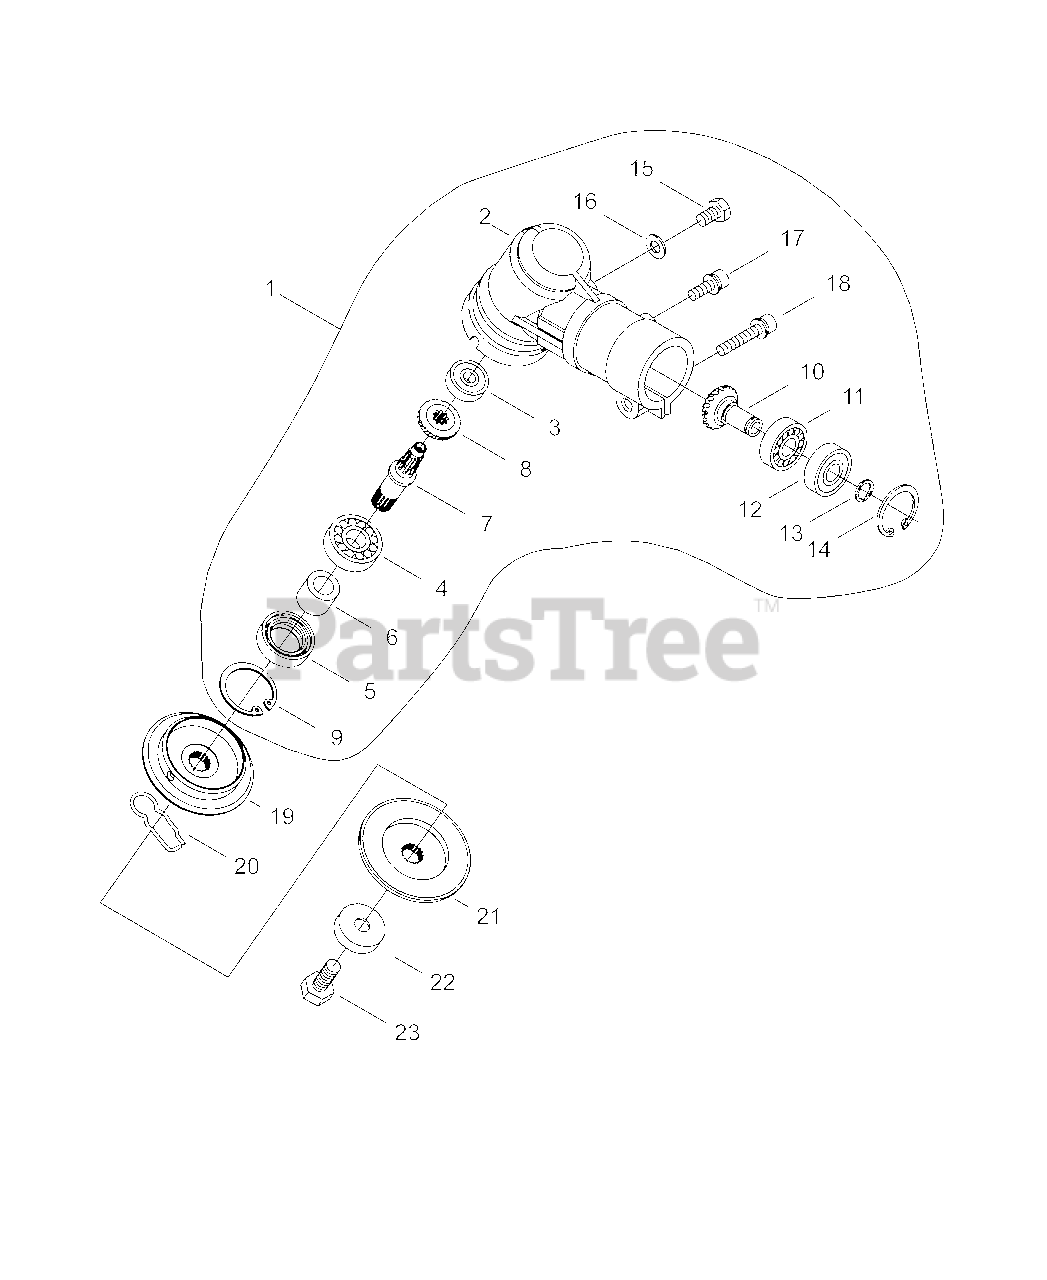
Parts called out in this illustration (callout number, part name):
1	GEAR CASE ASSY
2	HOUSING, GEAR CASE
3	BEARING, BALL 6000DDU
4	BEARING, BALL 6202
5	SEAL, OIL
6	COLLAR
7	SHAFT, GEAR
8	GEAR, BEVEL
9	RING, SNAP Ø35
10	GEAR, PINION
11	BEARING, BALL 6001
12	BEARING, BALL 6001ZZ
13	RING, SNAP Ø12
14	RING, SNAP Ø28
15	BOLT M6×10
16	WASHER
17	BOLT M6×14
18	BOLT M6×28
19	PLATE, ADAPTOR - UPPER
20	PIN, SLIDE
21	HOLDER
22	GUARD, BOLT
23	BOLT 10×30
